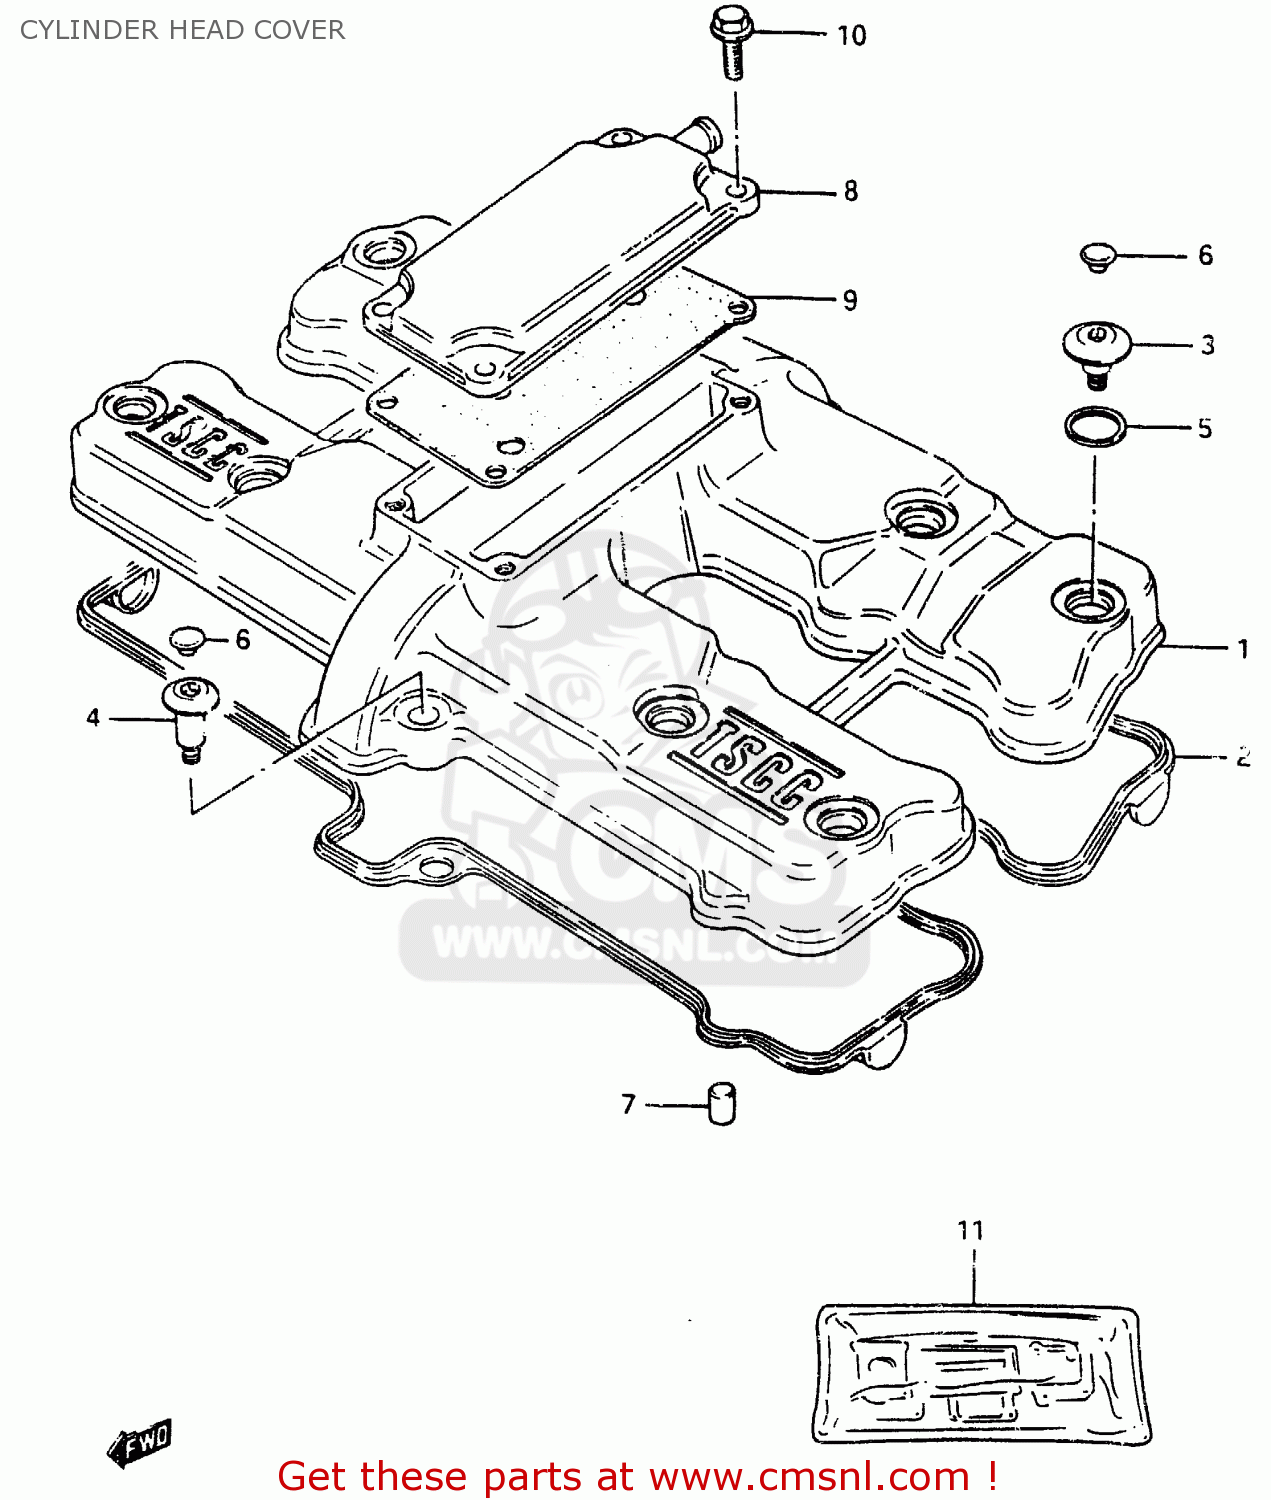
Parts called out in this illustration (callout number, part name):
1	COVER,CYLINDER
2	GASKET,HEAD COVER (NAS)
3	BOLT(7X5.5)
4	BOLT(7X19)
5	WASHER
6	CAP(OD:10)
7	PIN
8	COVER,BREATHER
9	GASKET (MCA)
10	BOLT
11	GASKET SET
